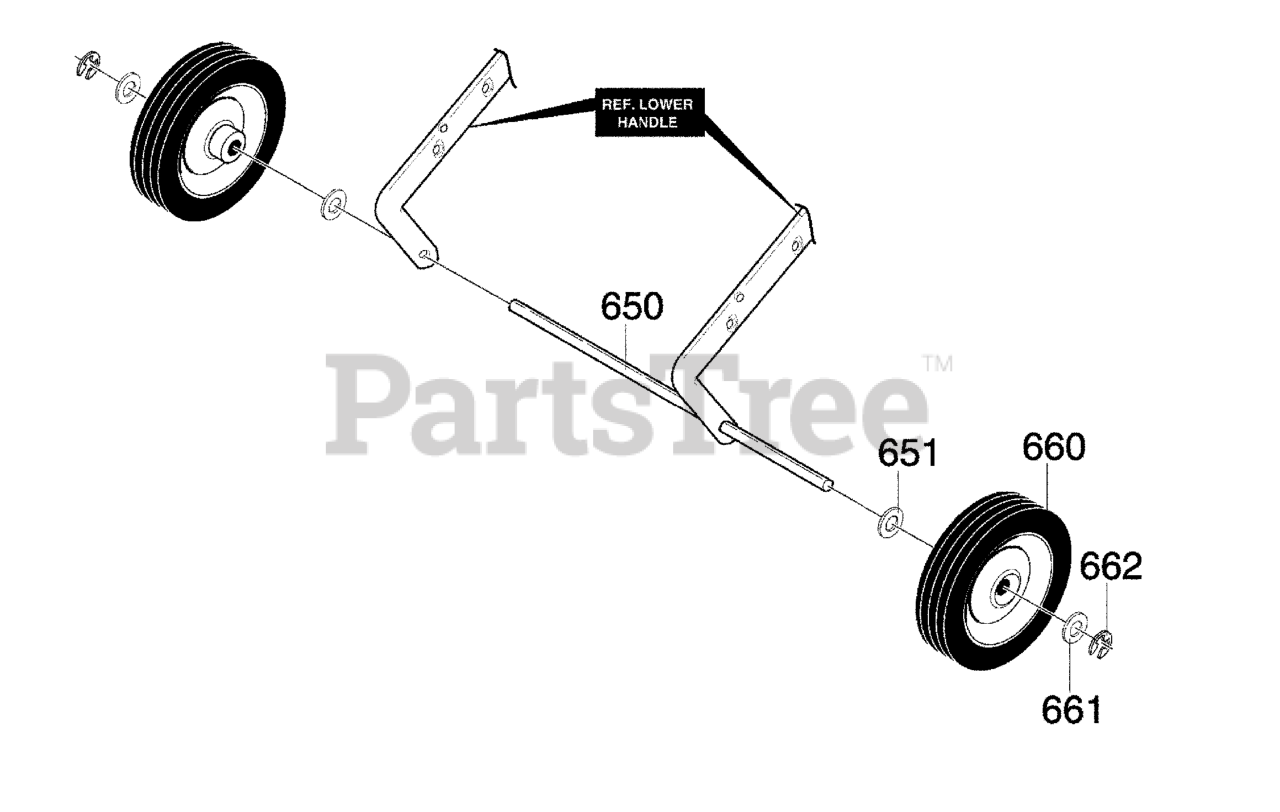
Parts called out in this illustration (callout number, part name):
650	AXLE SHAFT
651	WASHER, FLAT .391X1.00X1.25
660	TIRE & RIM
661	WASHER, FLAT .391X1.00X.125
662	RING, RET E
